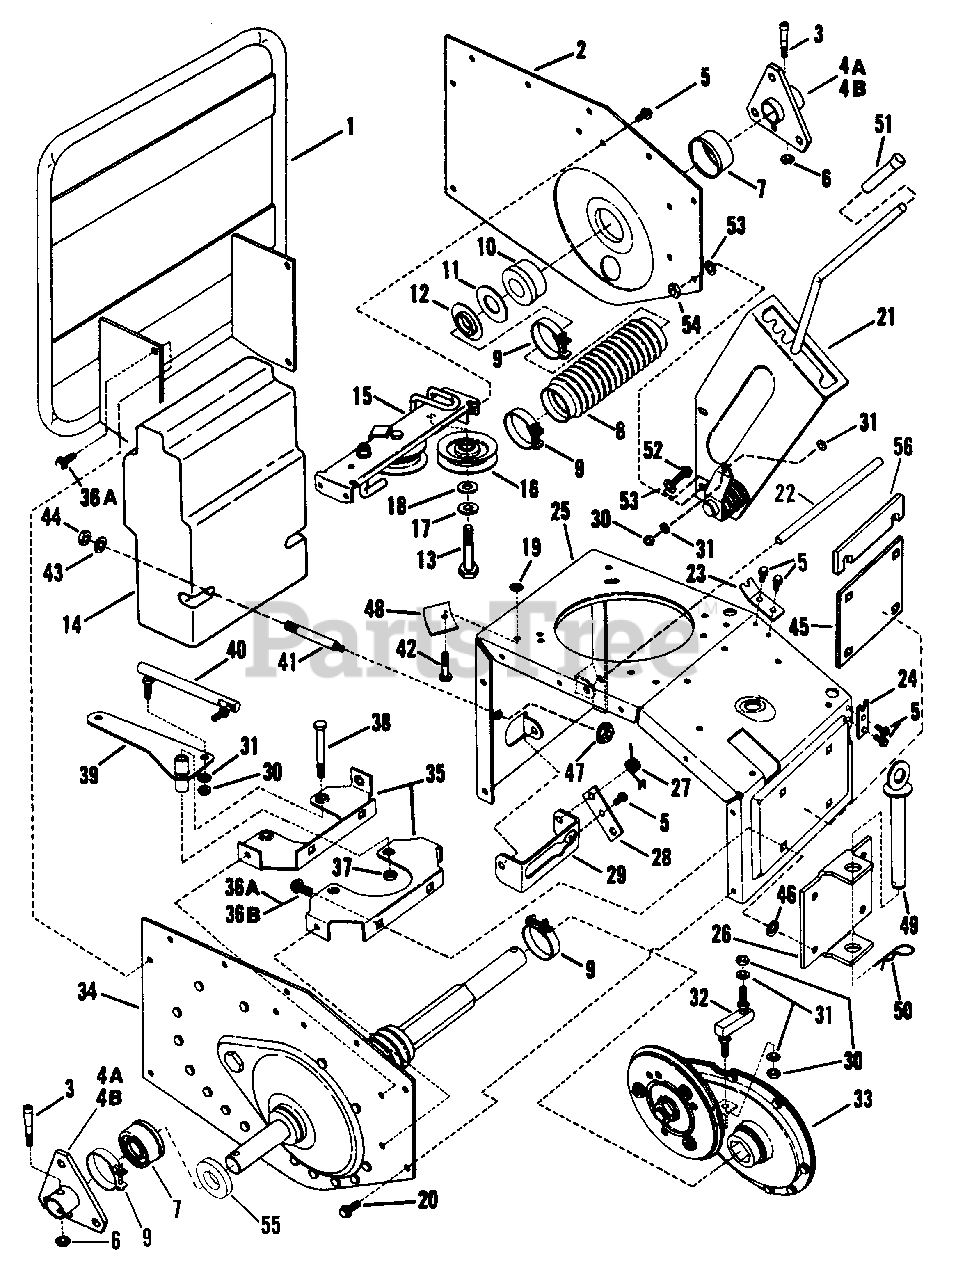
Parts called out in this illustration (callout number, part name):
1	BAR, Stand Up
2	FRAME, R.H. Side
3	BOLT, 5/16-24 x 1-5/8" Tapered
4A	HUB, Wheel, 3 Hole 3/4" ID 1.38" Long Tube
4B	HUB, Wheel, 3 Hole 3/4" ID 2.81" Long Tube
5	SCREW, 1/4-20 x 3/8" Hex Washer Self-Tap
6	NUT, 5/16-24 Hex Lock
7	CAP, Dust
8	SEAL, Long
9	CLAMP, 1-7/8 ZP
10	BEARING, Axle .75" ID x 1.626"/1.75" OD x 1.75" Long
11	WASHER, Thrust Nylon
12	WASHER, Thrust
13	SCREW, 3/8-16 x 1-1/2" Hex Head Cap, Grade 5
14	WEIGHT (approximately 60 pounds)
15	ASSEMBLY, Idler Bracket
16	PULLEY, V-Idler 2.62" OD
17	WASHER, 3/8" Split Lock
18	WASHER, 3/8" SAE Flat
19	RETAINER, 5/16" Bolt
20	SCREW, 5/16-18 x 1/2" Hex Washer Self-Tap
21	(NLA) ASSEMBLY, Shift Quadrant
22	(NLA) ROD
23	(NLA) CLIP, Cable
24	(NLA) CLIP, Control
25	FRAME
26	CLEVIS
27	(NLA) SPRING
28	(NLA) LEVER
29	YOKE, Clutch
30	NUT, 5/16-24 Hex
31	WASHER, 5/16" Split Lock
32	LINK, Short Shift 1"
33	ASSEMBLY, Primary Chain Case
34	ASSEMBLY, Drive L.H. Frame
35	BRACE
36A	SCREW, 3/8-16 x 1" Self-Tap
36B	BOLT, 3/8-16 x 1" Square Neck Carriage
37	NUT, 3/8-24 Hex Center Lock
38	BOLT, 5/16-24 x 2-5/8 Shoulder
39	BELLCRANK, Shift
40	LINK, Long Shift 4.5"
41	STUD, Weight
42	SCREW, 5/16-24 x 1-1/2" Hex Head Cap, Grade 2
43	WASHER, 7/16" SAE Flat
44	NUT, 7/16-14 Hex Center Lock, Grade A
45	(NLA) SPACER, Tiller Head
46	RETAINER, 3/8" Bolt
47	NUT, 5/16-18 Hex Flange Lock
48	(NLA) WASHER, Engine
49	PIN, Clevis (Hitch) 34" x 6 1/16"
50	HAIR PIN, 2.25, .093 ZP
51	GRIP
52	SCREW, 5/16-18 x 1" Hex Washer Self-Tap
53	WASHER, 5/16" Internal/External Tooth Lock
54	NUT, 5/16" Hex Center Lock
55	SEAL, OIL .750" ID x 1.832" OD
56	(NLA) SPACER, Tiller Head
